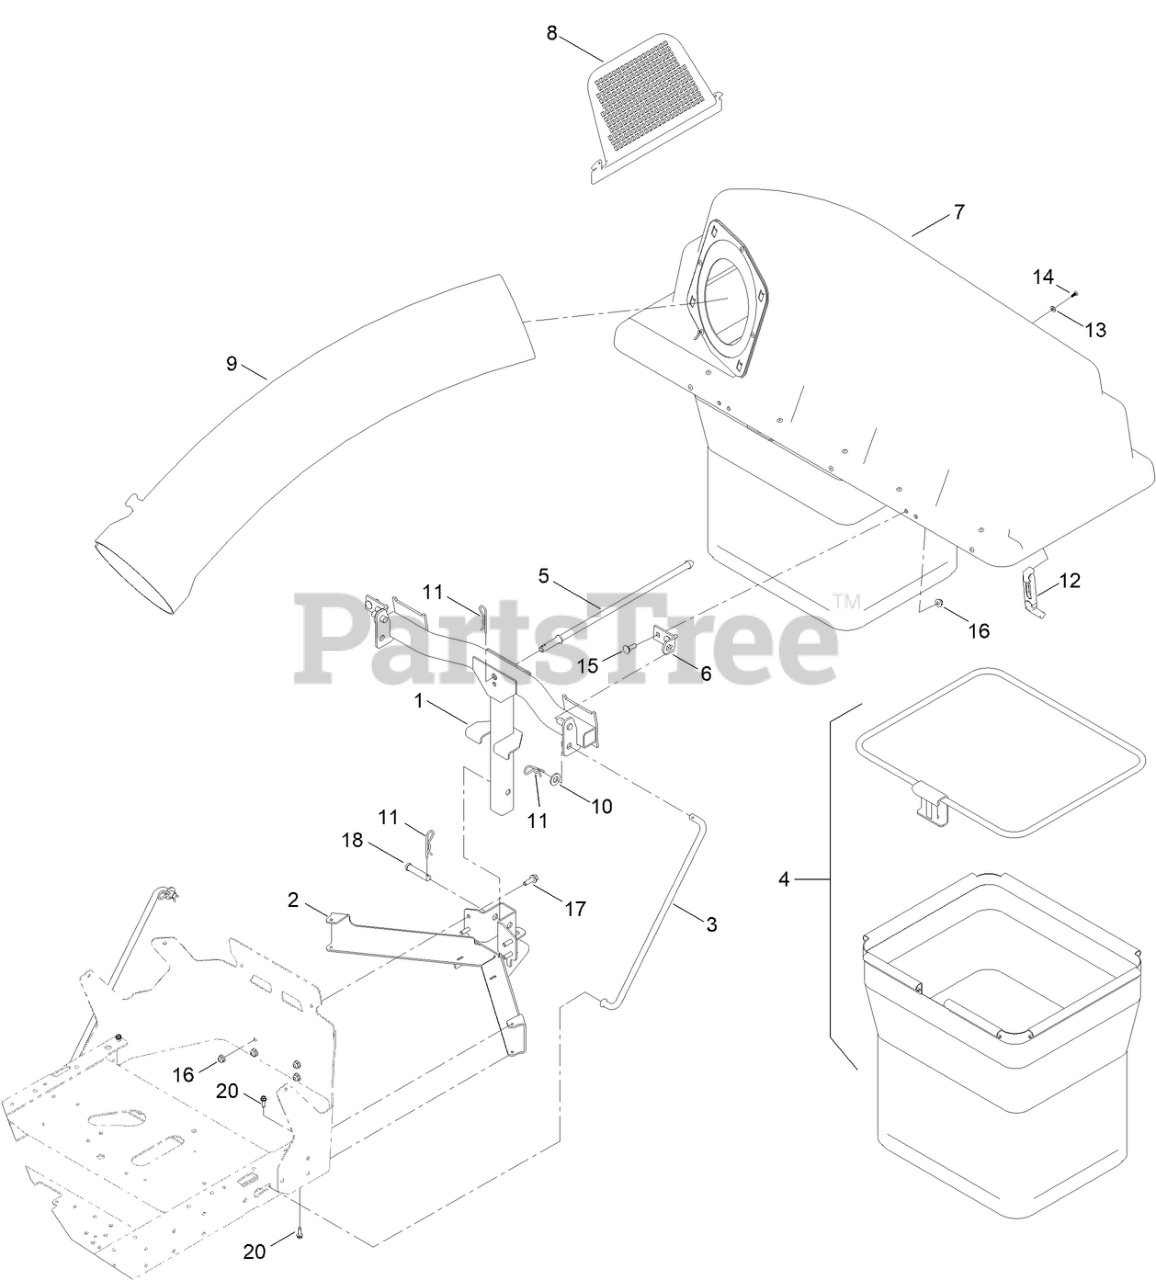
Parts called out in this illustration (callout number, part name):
1	FRAME ASM PIVOT [BLACK]
2	MOUNT-LOWER, BAGGER [BLACK]
3	ROD-SUPPORT, CZ
4	BAG ASM
5	ROD-HOOD, DOWN (HOLD)
6	BRACKET-HOPPER PIVOT
7	TOP ASM-BAGGER
8	SCREEN-BAGGER
9	TUBE-BAGGER
10	WASHER-FLAT
11	PIN-HAIR
12	LATCH-RUBBER
13	WASHER-PLAIN
14	SCREW-PLASTIC, PTH
15	BOLT-CARR
16	NUT-HF
17	SCREW-HHF
18	PIN-CLEVIS
20	SCREW-HWHTF
